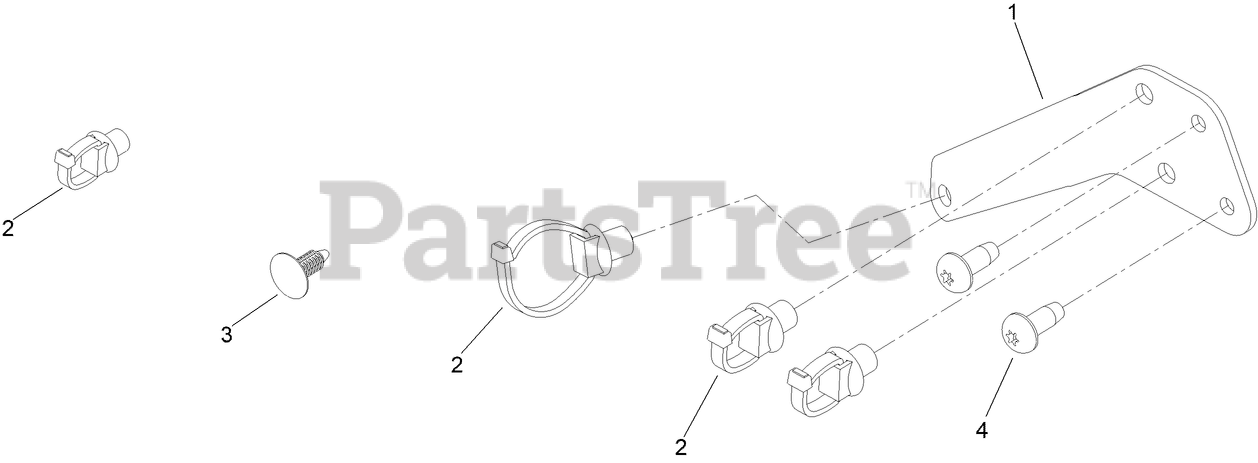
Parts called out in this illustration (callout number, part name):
1	BRACKET-SUPPORT
2	CLIP-TIE
3	PLUG-PLASTIC
4	SCREW-TPH THD FORM
